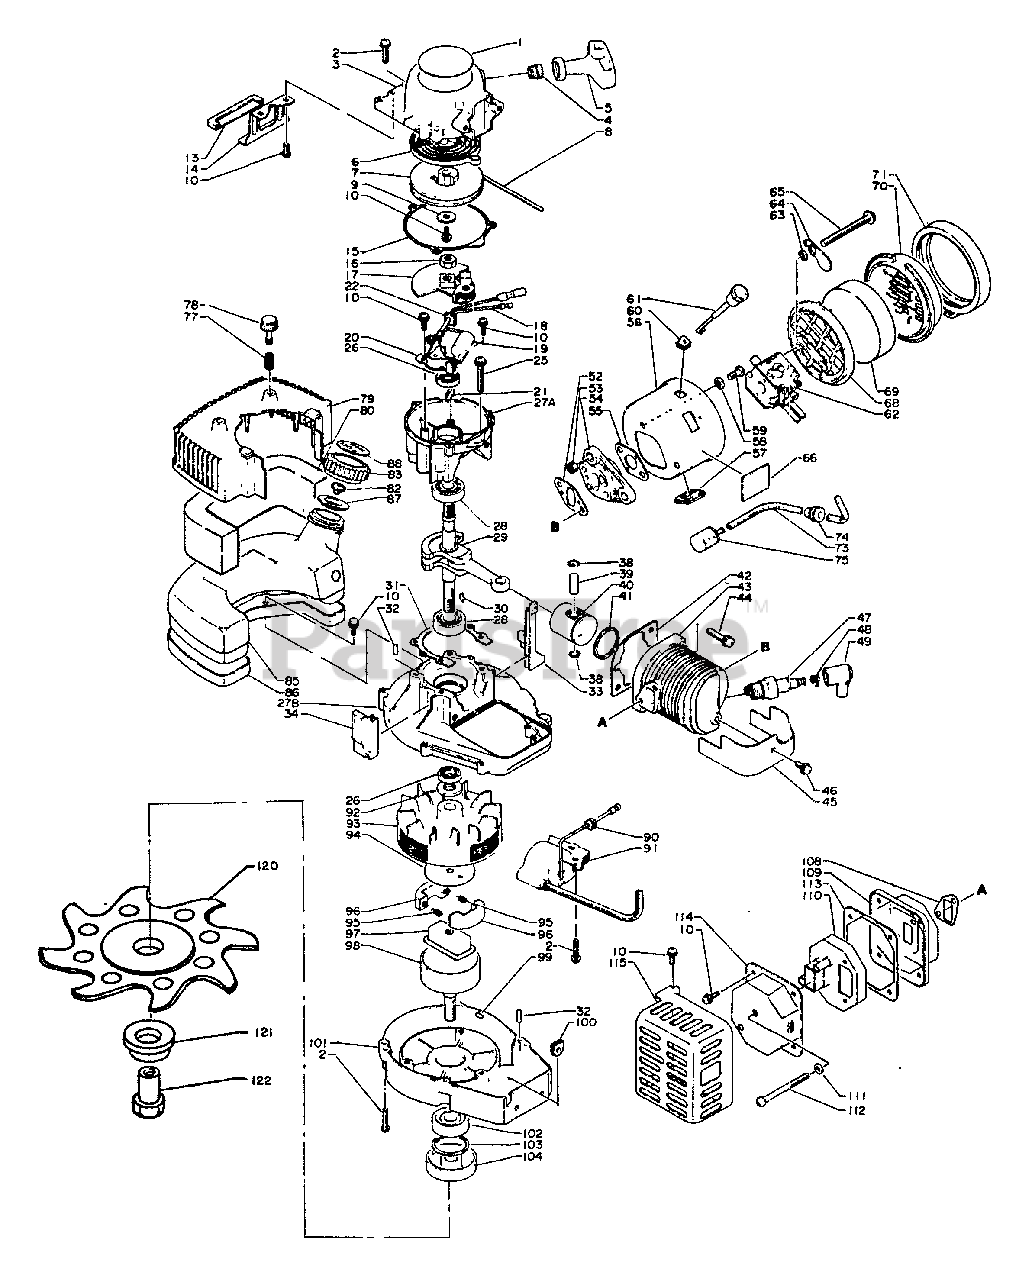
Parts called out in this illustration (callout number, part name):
1	LABEL - ECHO
2	SCREW - 4X20
3	CASE, STARTER
4	GUIDE, ROPE
5	GRIP, STARTER
6	SPRING, REWIND
7	REEL, ROPE
8	ROPE, STARTER - 3X850
10	SCREW - 4X10
13	CUSHION
14	BRACKET, FUEL TANK
15	GASKET, STARTER
17	STARTER PAWL ASSY
18	LEAD
19	CONDENSER
20	CONTACT POINT SET
21	PAD, OIL
25	SCREW - 5X30
26	SEAL, OIL
27	CRANKCASE KIT
27A	CRANKCASE KIT
27B	CRANKCASE KIT
28	BEARING, BALL - 6200
29	CRANKSHAFT ASSY
31	GASKET, CRANKCASE
32	PIN - LOCATING
33	SEAL, DUST
34	Dust seal plate (B)
38	RING, RETAINING
39	PIN, PISTON
40	PISTON
41	RING, PISTON
42	GASKET, CYLINDER
43	CYLINDER
44	SCREW - 6X22
45	SHIELD, CYLINDER
46	SCREW - 5X10
47	SPARK PLUG -- BM-6A
48	TERMINAL, SPARK PLUG CAP
49	CAP, SPARK PLUG
52	GASKET, INTAKE
54	INSULATOR, INTAKE
55	GASKET, INTAKE
56	CASE, CARBURETOR
57	GROMMET
58	LOCKWASHER - 5
59	LOCKWASHER - 5
60	GROMMET
61	ROD, CHOKE
62	CARBURETOR
63	WASHER - 5
64	SHUTTER, CHOKE
65	SCREW - 5X57
68	RETAINER, AIR FILTER
69	FILTER, AIR
70	COVER, AIR FILTER
71	COVER, AIR FILTER
73	PIPE - FUEL
75	FILTER, FUEL
77	SPRING
78	THUMBSCREW
79	SEAL, DUST
80	SEAL, DUST
83	CAP
85	TANK, FUEL
86	BRACKET, FUEL TANK
87	HOLDER, VENT
88	LABEL - FUEL MIX
91	COIL, IGNITION
93	FLYWHEEL
94	PLATE, CLUTCH
95	SPRING, CLUTCH
96	SHOE, CLUTCH
97	HUB, CLUTCH
98	DRUM, CLUTCH
99	PIN - 3X6
101	CASE, FAN
102	BEARING, BALL - 6201
103	RING, RETAINING - 32
104	ADAPTOR, BLADE - UPPER
108	GASKET, EXHAUST
109	MUFFLER
110	SILENCER
111	WASHER - 5
112	SCREW - 5X55
113	GASKET, EXHAUST
114	GUIDE, EXHAUST
115	COVER, MUFFLER
121	ADAPTOR, BLADE - LOWER
122	NUT
